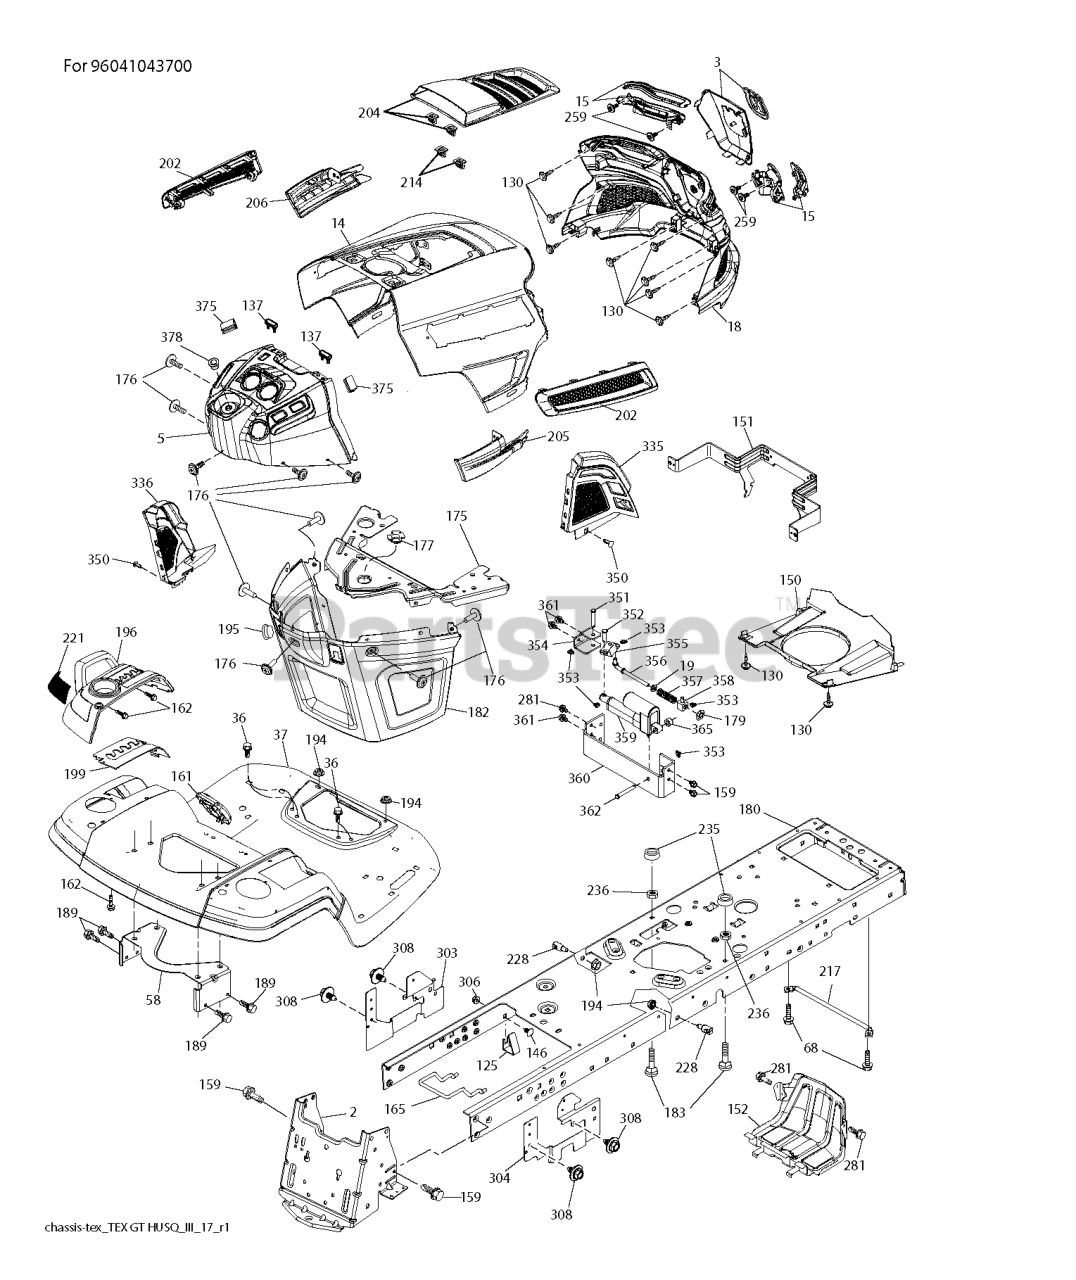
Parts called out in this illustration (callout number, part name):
2	DRAWBAR.STGT
5	DASH.UPPER.ASM.GT2.D_R.PTO.ELC
14	HOOD.ASM.HUSQVARNA.GT.TEX.ORAN
15	Service Kit
36	SCREW 5/16"
37	FENDER.PNT.TX.GT.CH/FW/DL.HUSQ
58	BRKT.SUPPORT.FNDR/TANK
125	CLIP.FUEL.LINE
137	BUMPER DASH
146	BOLT.RDHD.SHT.SQNK.3/8-16X5/8
150	AIR.DUCT.GTV.BLACK
151	BRACKET.PIVOT.HOOD.GT.HUSQ.II
152	SHIELD.BROWNING.PNT.GT.V2
159	SCREW, 3/8-16X3/4
161	CONSOLE.WINDOW.FUEL.HUSQ.GT
165	SUPPORT.TANK.REAR.B/TE
175	PLATE.PNT.CROSSMEMBER.HUSQ/PRE
176	SCREW.#10-24X5/8.RN.QU
177	BUSHING STEERING
180	CHASSIS.LT/GT.BOLTED
182	DASH.LOWER.COMMON.12V.ADAPTOR
189	SCREW
195	PLUG.HOLE.DASH.LOWER.12V.BLK
196	SUBASM.CONSOLE.HUSQ.GT.DECKLFT
199	PLATE.DECK.LIFT.HUSQVARNA.GT
202	Vents
205	SIDE.TRIM.RH.GT.HUSQ.II
206	SIDE.TRIM.LH.GT.HUSQ.II.GRAY
214	CLIP.RETAINER.TINNER.
217	ROD.PIVOT.HOOD
221	REFLECTOR.LH.TEX GT HU
228	STUD.W/"D"ANTI-ROTATION
236	NUT.CENTERLOCK.5/16-
281	SCREW 3/8-16X1
303	SHIELD.LWR.LH.LTGT.NON30
304	SHIELD.LWR.RH.LTGT.NON30.NOTCH
306	NUT LOCK FLG 3/8-16 UNC
308	BOLT.5/16-18UNCX3/4 W/SEMS.BLK
335	COVER.LOWER.DASH.RH.BLACK
336	COVER-LH.LOWER.DASH.GT2.BLACK
350	CLIP.X-MAS.TREE
351	PIN.CLEVIS.375X2.125
352	PIN.CLEVIS.(.375 X 1.25)
353	CLIP RETAINER
354	SUPPORT.DIFF.LOCK.BELLCRANK.
355	BELLCRANK.PIVOT.LOCK.DIFF
356	LINK.LOCK.DIFF
357	SPRING.COMPRESSION
358	SWIVEL.GUIDE
359	ACTUATOR.ELECTRIC
360	BRACKET.ACUATOR
362	PIN.CLEVIS.(.375 X 2.42)
365	SPACER.NYLON.75" X .4375
375	BUMPER CLIP-ON. DASH 1"
378	BUSHING FLANGE; PLASTIC
